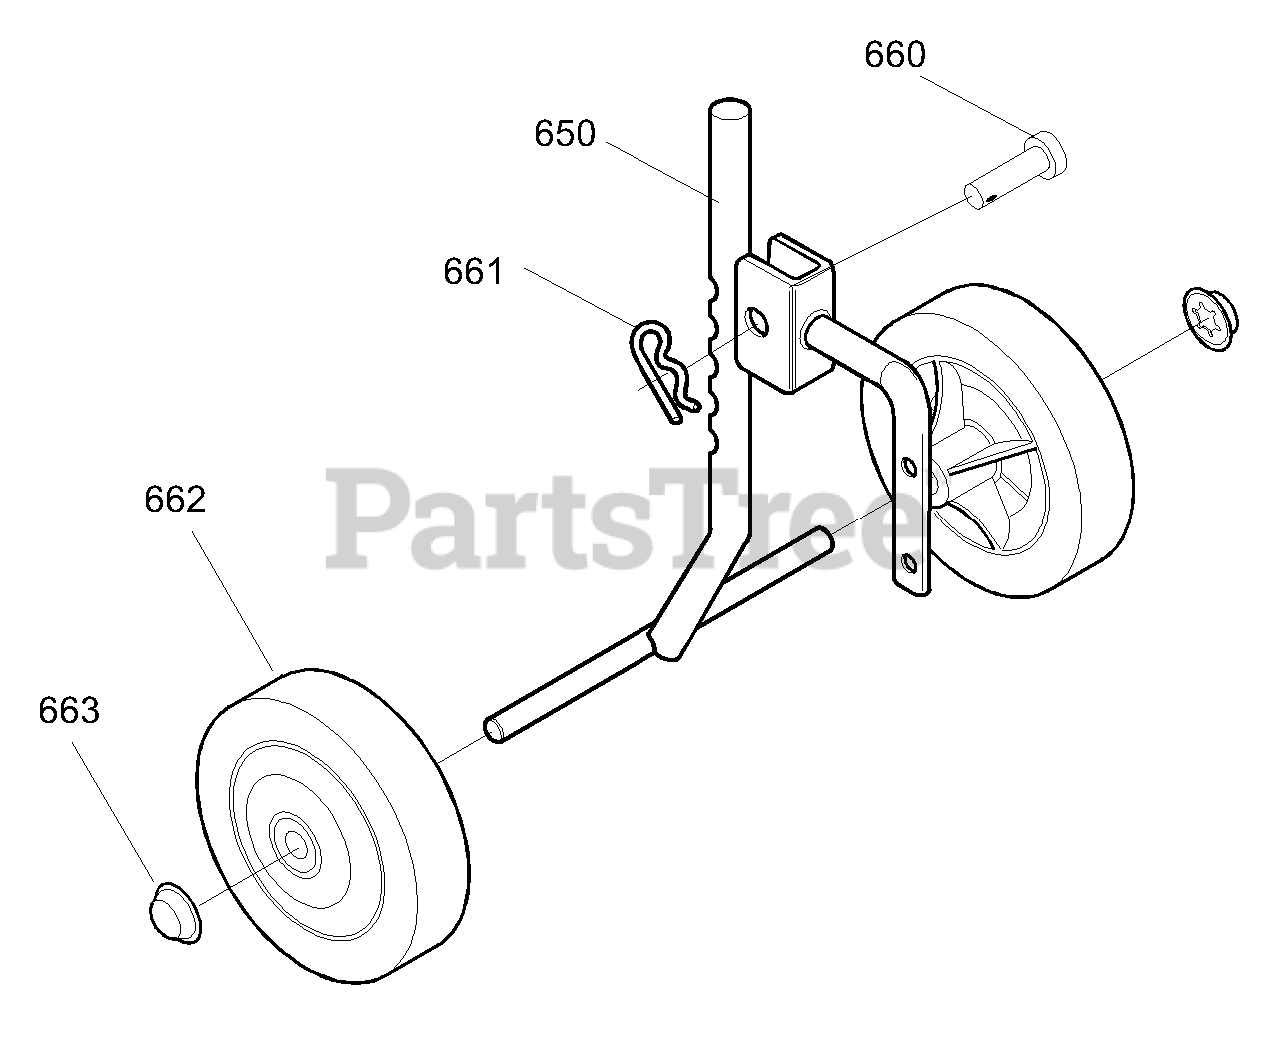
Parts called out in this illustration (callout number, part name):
650	Wheel Support Assy.
660	Clevis Pin
661	Hair Pin
662	Tire & Rim
663	Push On Nut
